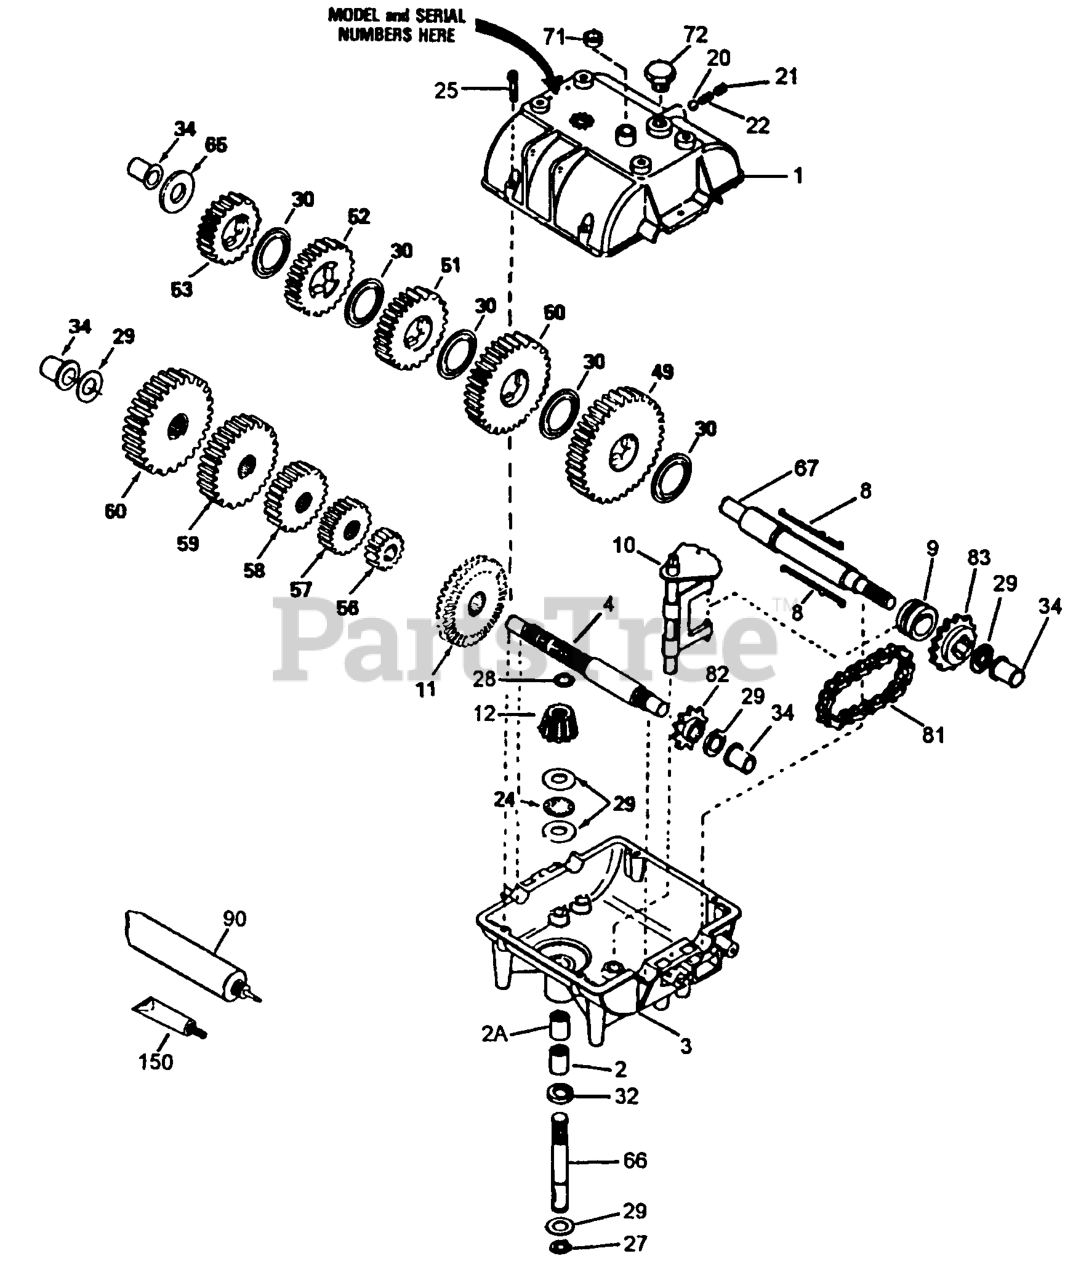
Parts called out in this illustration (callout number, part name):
1	Transmission Cover
2	Needle Bearing
2A	Needle Bearing
3	Transmission Case
4	Countershaft
8	Shift Key
9	Shift Collar
10	Shift Rod & Fork
11	Bevel Gear (42 Teeth)
12	Input Bevel Pinion (14 Teeth-Steel)
20	Steel Ball, 5/16" Dia.
21	Set Screw, 3/8-16 X 3/8"
24	Thrust Bearing
25	Screw, 1/4-20 X 1-1/4"
27	Retaining Ring
28	Retaining Ring
32	"O" Ring
34	Flanged Bushing
49	Spur Gear (37 Teeth)
50	Spur Gear (35 Teeth)
51	Spur Gear (32 Teeth-Steel)
52	Spur Gear (30 Teeth)
53	Spur Gear (25 Teeth)
56	Spur Gear (12 Teeth-Steel)
57	Spur Gear (15 Teeth)
58	Spur Gear (18 Teeth-Steel)
59	Spur Gear (20 Teeth)
60	Spur Gear (25 Teeth)
66	Input Shaft (3-11/16" Long)
67	Shifter & Brake Shaft
71	Square Cut Ring
72	Threaded Plug
81	Roller Chain (No. 41 Chain, 24 Links)
82	Sprocket (9 Teeth)
83	Sprocket (18 Teeth)
90	Grease (32 Oz. Bottle Bentonite Grease)
